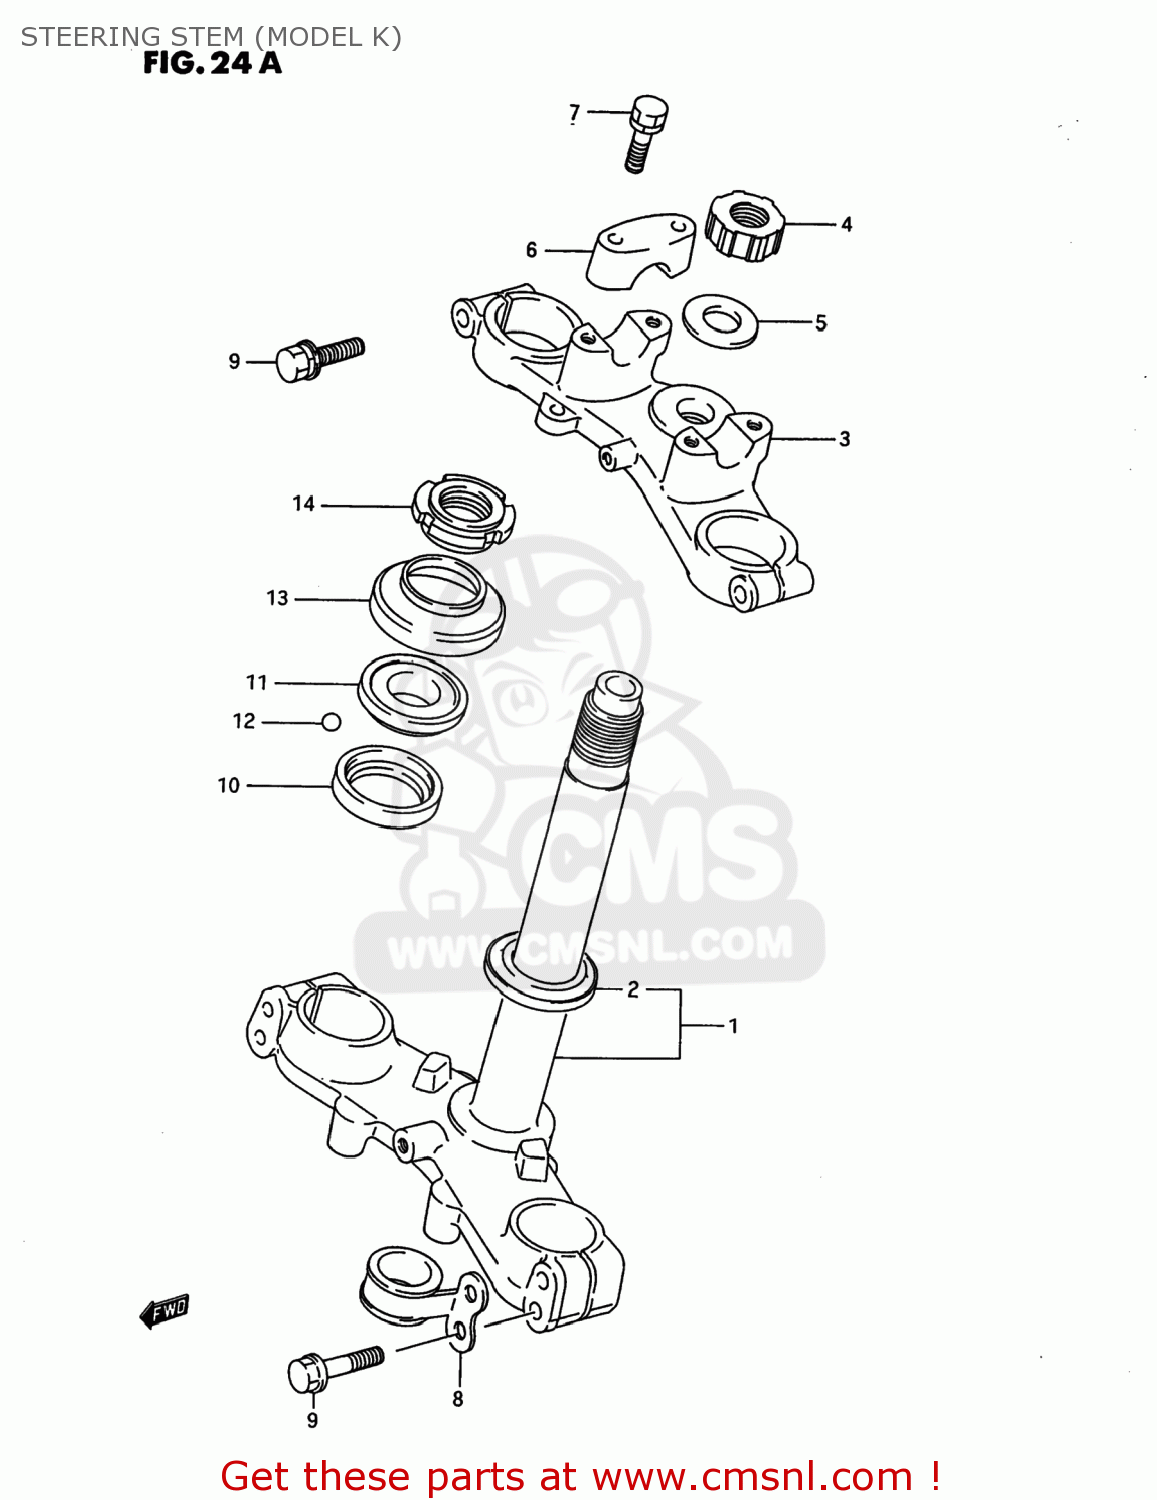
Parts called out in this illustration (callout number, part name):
1	STEM,STEERING
2	RACE
3	STEM HEAD,STEERING
4	NUT,STEM HEAD
5	WASHER
6	HOLDER,HANDLEBAR
7	BOLT
8	CLIP
9	BOLT 8X40
10	RACE,STEERING INNER (SUJ)
11	RACE,STEERING,OUTER,UPPER
12	BALL
13	DUST SEAL,STEERING,UPPER
14	NUT,STEERING STEM(25X44X10)
